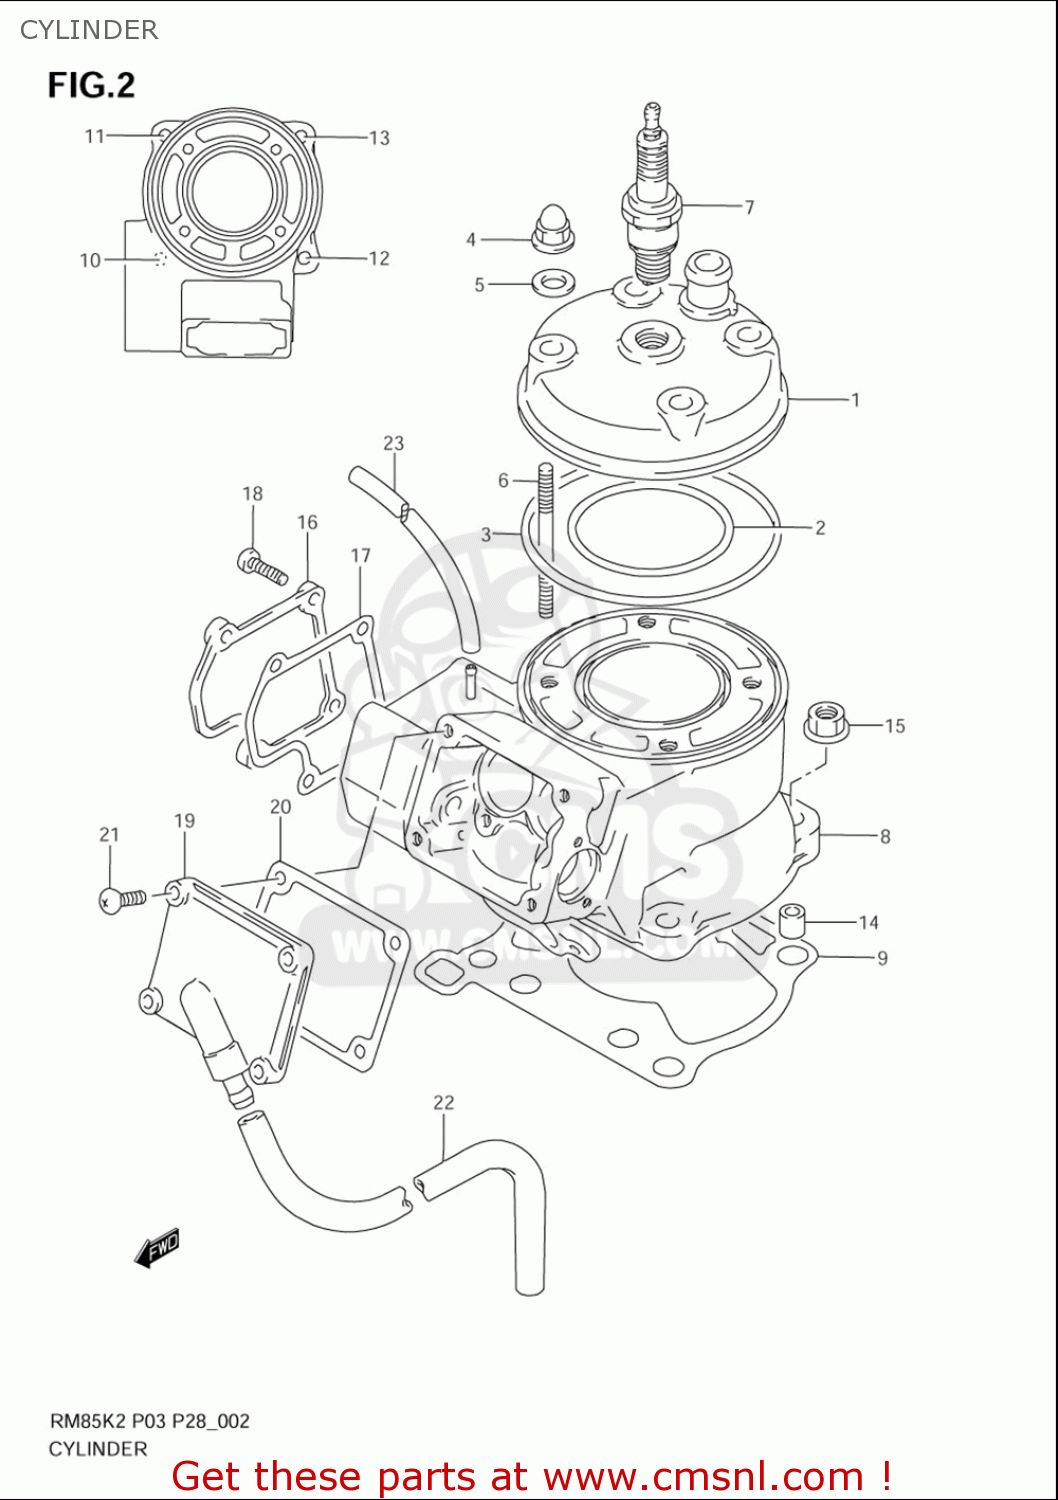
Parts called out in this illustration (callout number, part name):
1	HEAD,CYLINDER
2	O RING,CYLINDER HEAD NO.1
3	O RING,CYLINDER HEAD NO.2
4	NUT
5	GASKET(8.5X17X2.3) (NAS)
6	BOLT,STUD
7	PLUG,SPARK(BR10ES)
8	CYLINDERSET
9	GASKET,CYLINDER (NAS)
10	BOLT,STUD
11	STUD 8X25
12	BOLT,STUD
13	STUD BOLT
14	PIN(8.4X11X14)
15	NUT
16	COVER,CYLINDER NO.1
17	GASKET,CYLINDER COVER NO.1 (NAS)
18	SCREW
19	COVER,CYLINDER
20	GASKET,CYL COVER NO.2 (NAS)
21	SCREW
22	HOSE(5X8.2X600)
23	HOSE(5X8.2X600)
